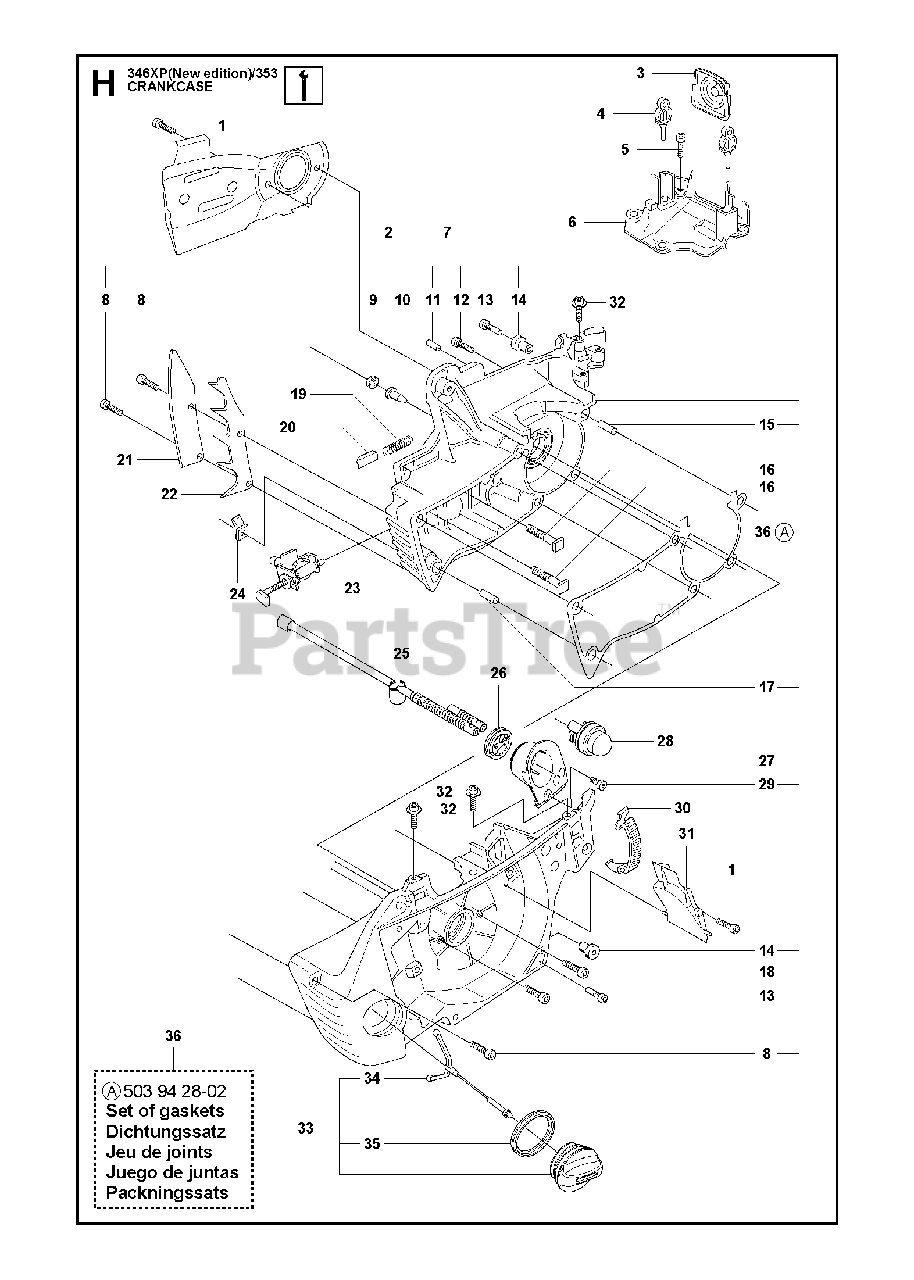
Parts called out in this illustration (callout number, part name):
2	CHAIN GUIDE PLATE
6	CARBURETOR AREA BASE
7	CRANKCASE ASSY
8	SCREW
9	PLUG
10	VALVE-CHECK (DUCKBILL)
11	PIN
12	SCREW
13	SCREW
14	MOVEMENT LIMITER
15	SLEEVE
16	BOLT
17	SLEEVE
18	SCREW
19	LOCK SPRING
22	FELLING DOG
23	CHAIN TENSIONER
24	CHAIN CATCHER
27	BRACKET
28	AIR PURGE BUBBLE
29	SCREW IHSCT
30	CLIP GRAY
33	OIL TANK CAP GREY
34	TANK LOCK
35	OILCAP GASKET
36	GASKET SET
